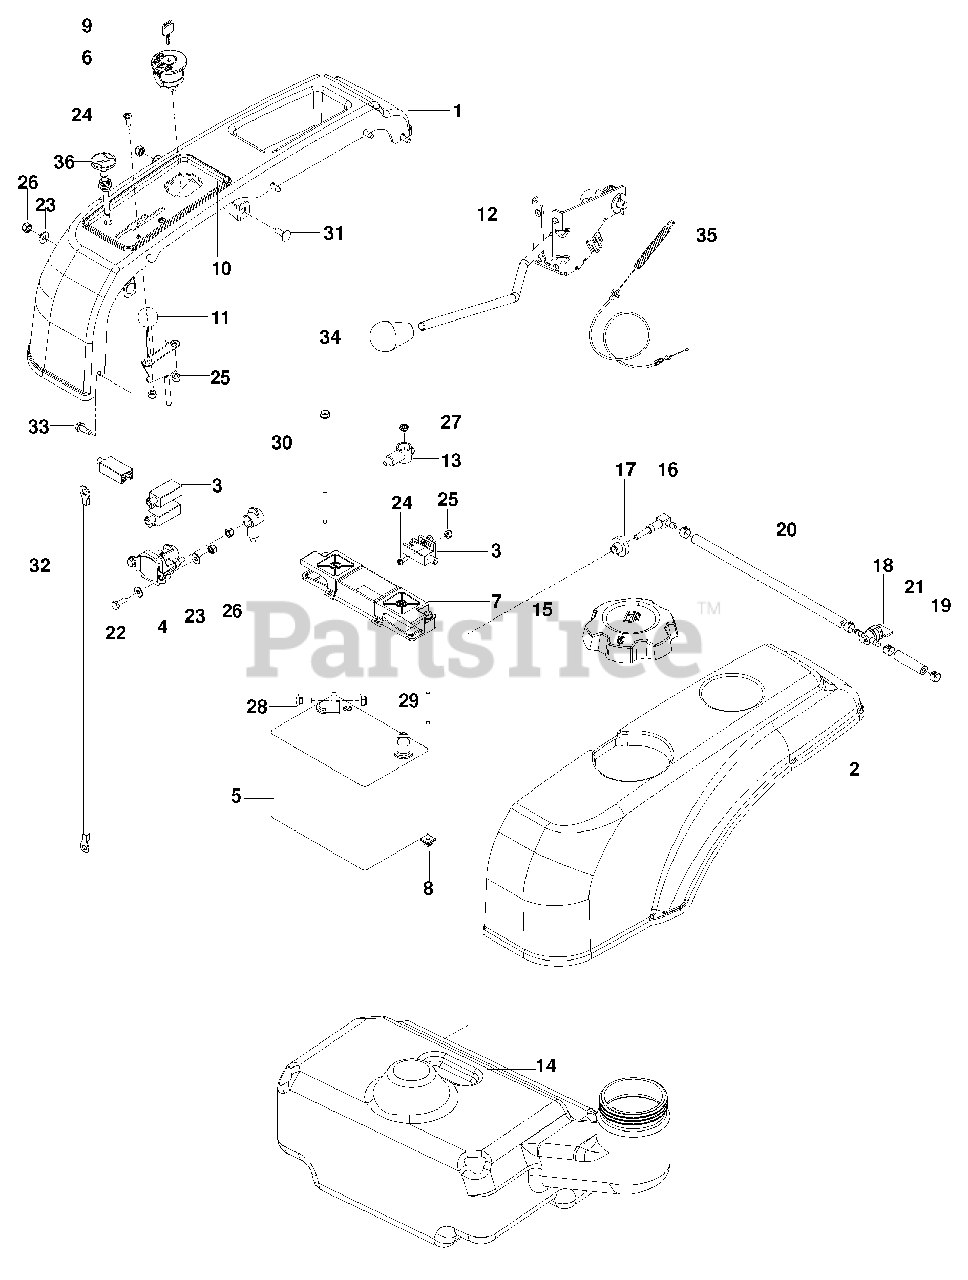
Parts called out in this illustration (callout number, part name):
1	FENDER, RH
2	FENDER, LH
5	BATTERY
6	SWITCH, IGNITION
7	BATTERY HOLD DOWN
8	NUT 1/4 PUSH NYLON
9	KEY, IGNITION
10	PANEL, CONTROLS
11	CABLE, THROTTLE
12	CLUTCH ASSY w/ CABLE
13	TERMINAL COVER, SM
14	TANK, FUEL
16	ELBOW w/ FILTER
17	FITTING, TANK
18	VALVE, FUEL
19	CLAMP, HOSE
20	HOSE 1/4 x 8
21	HOSE 1/4 x 2
22	HCS 1/4-20 x 3/4
23	WASHER 1/4 FLAT SAE
24	SCREW #10-24 x 5/8
25	NUT #10-24 HEX NYLOC
26	NUT 1/4-20 HEX NYLOC
27	NUT 1/4-20 HEX THIN NYLOC
28	RHSNB 5/16-18 x 3/4
29	NUT 5/16-18 FLANGE NYLOC
30	BOLT 1/4 x 7 1/2
31	RHSNB 1/4-20 x 3/4 GR2
32	BATTERY CABLE, NEGATIVE
33	SCREW 1/4-20 x 5/8 SLF TAP
34	KNOB, CLUTCH
35	CABLE, CLUTCH
36	CONTROL, CHOKE
